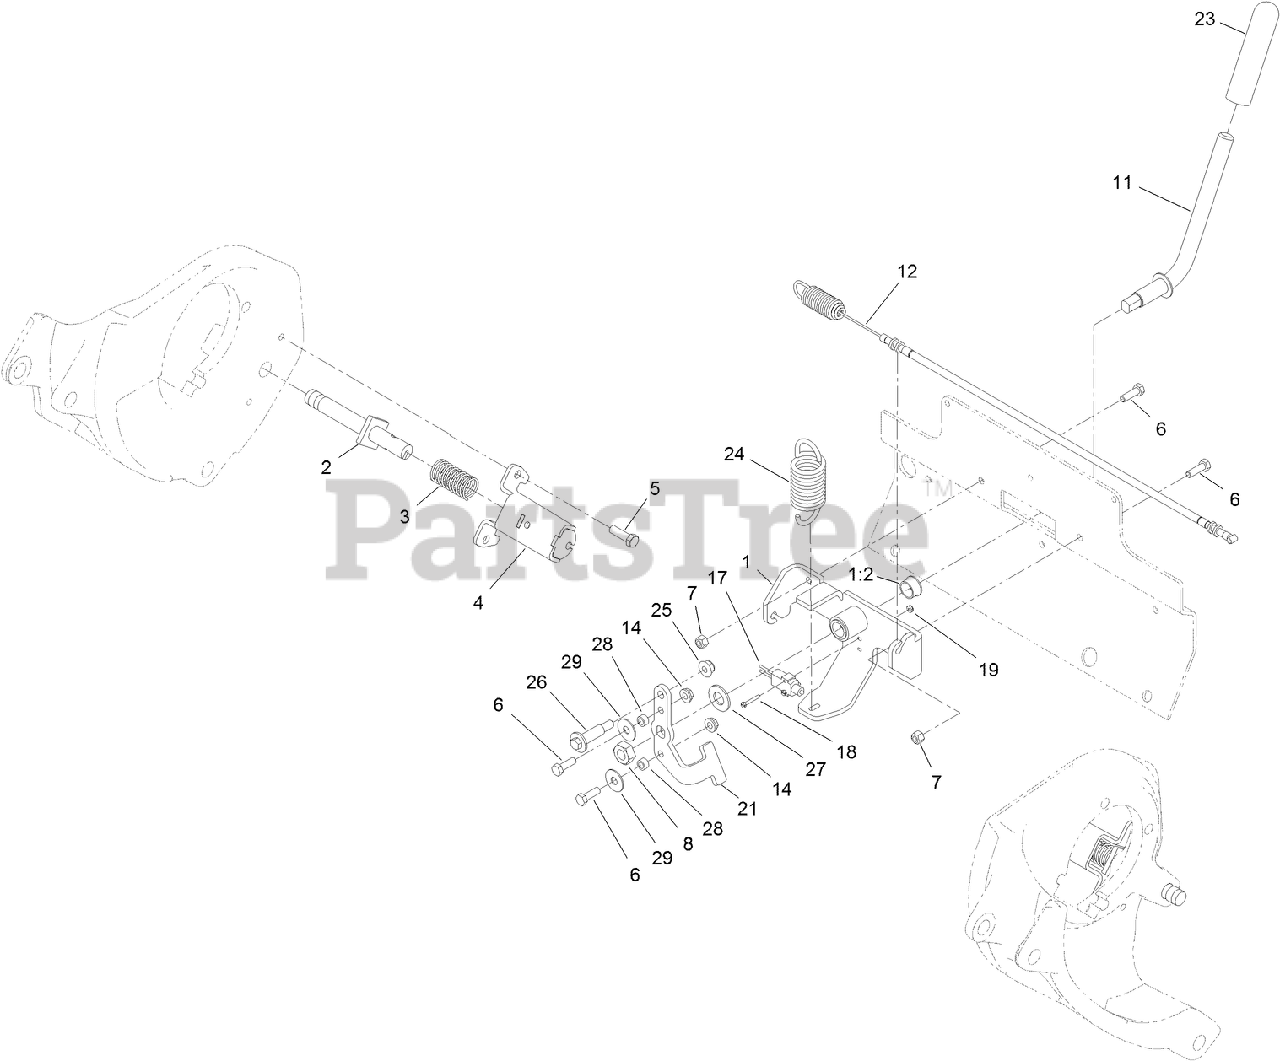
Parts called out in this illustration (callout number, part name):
1	BRACKET-BRAKE
1:2	BEARING-FLANGE
2	SHAFT ASM
3	SPRING-COMPRESSION
4	MOUNT-BRAKE
5	SCREW-HH
6	SCREW-HH
7	NUT-LOCK, NI
8	NUT-LOCK, NI
11	LEVER-BRAKE
12	CABLE-BRAKE
14	NUT-HF
17	SWITCH
18	SCREW
19	NUT-HEX
21	PLATE-BRAKE LINKAGE
23	GRIP-HANDLE
24	SPRING-EXT
25	NUT-HF, NI
26	BOLT-SHOULDER
27	WASHER-FLAT
28	SPACER-PIVOT, TILT
29	WASHER
